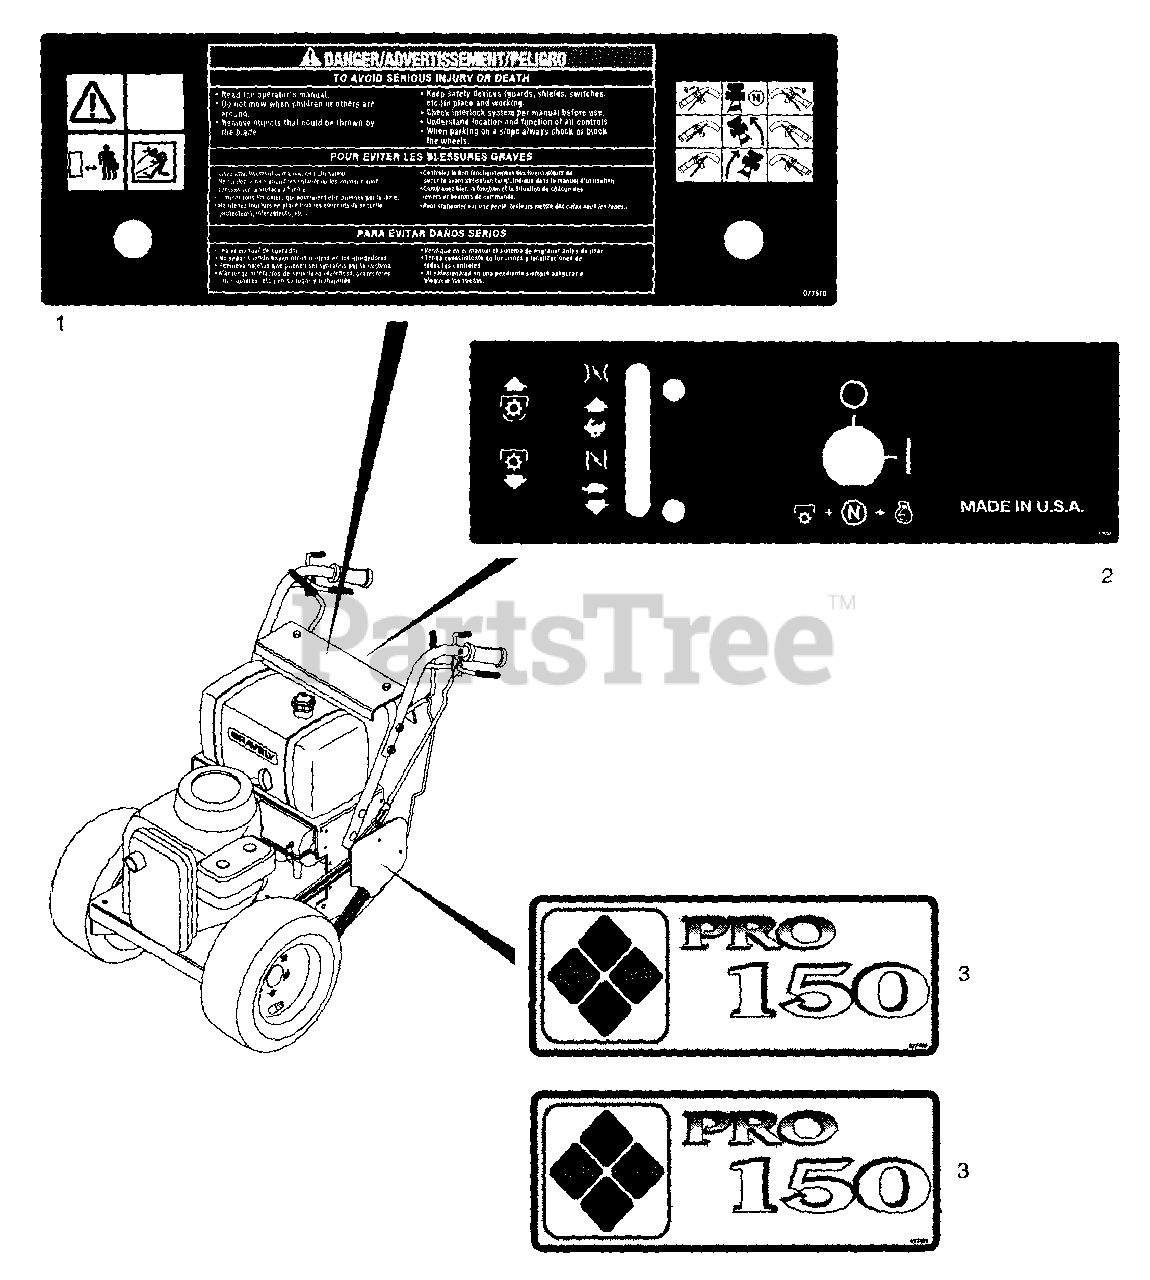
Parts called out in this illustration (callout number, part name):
1	Decal-Safety
2	Decal-Control Panel
3	Decal-Logo
